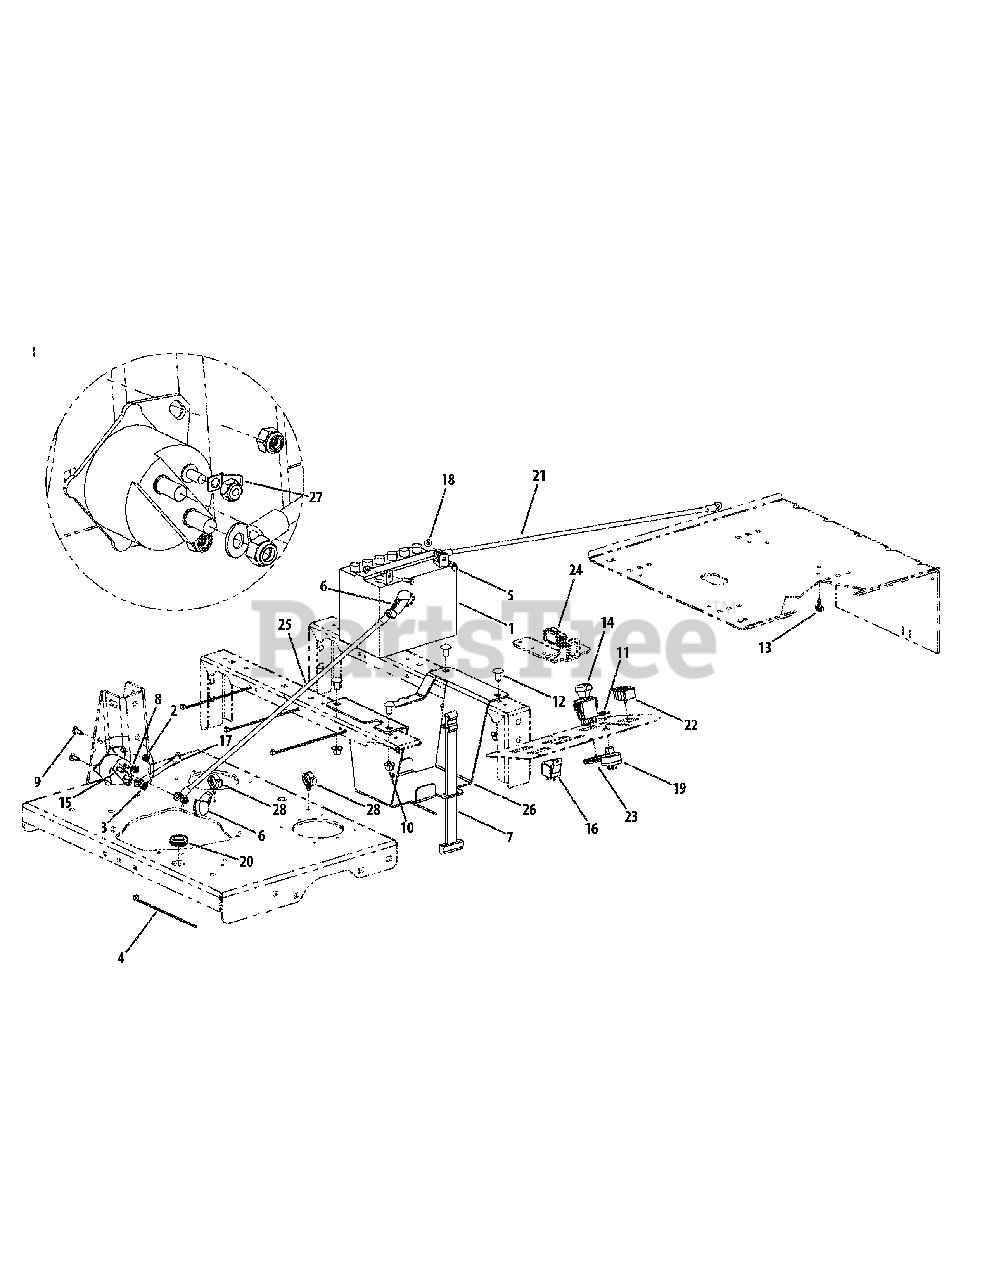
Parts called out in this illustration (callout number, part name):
1	Battery, 12V 225CCA 30 Min
2	Lock Nut w/Nylon Insert
3	Nylock Nut, 5/16-18 - 23HP
3	Nut, Flange Wiz - 31HP
4	Tie, Cable, 3/16 x .05 x 7.4"
5	Screw, Hex, Cap, 1/4-20 x .75
6	Boot, 1" OD Rubber Battery-PST, Red
7	Strap, Battery
8	Nut, Lock, Nylon Insert, #10-32
9	Carriage Bolt, 1/4-20 x .750
10	Hex Nut, Flange Lock, 3/8-16
11	Nut, W/Cap, 5/8-32 Ignition
12	Carriage Bolt, 3/8-16 x .75 Long
13	Electrical Conduit Clip, 3/8
14	Switch, Electric, PTO
15	Solenoid Magnetic Switch
16	Relay, 12V 40A
17	Cable, Battery Red, 5"
18	Hex Flange Lock Nut, 1/4-20
19	Switch, Ignition, 6 Pin includes:
20	Grommet, .75 ID
21	Cable, Battery Black, 34"
22	Meter, Hour
23	Bracket, PTO Switch Retainer
24	Switch, Safety N.O./N.C.
25	Cable, Battery Red, 42"
26	Battery Bracket
27	Terminal Tab, 1/4" Blade
28	Electrical Conduit Clip, 5/8
